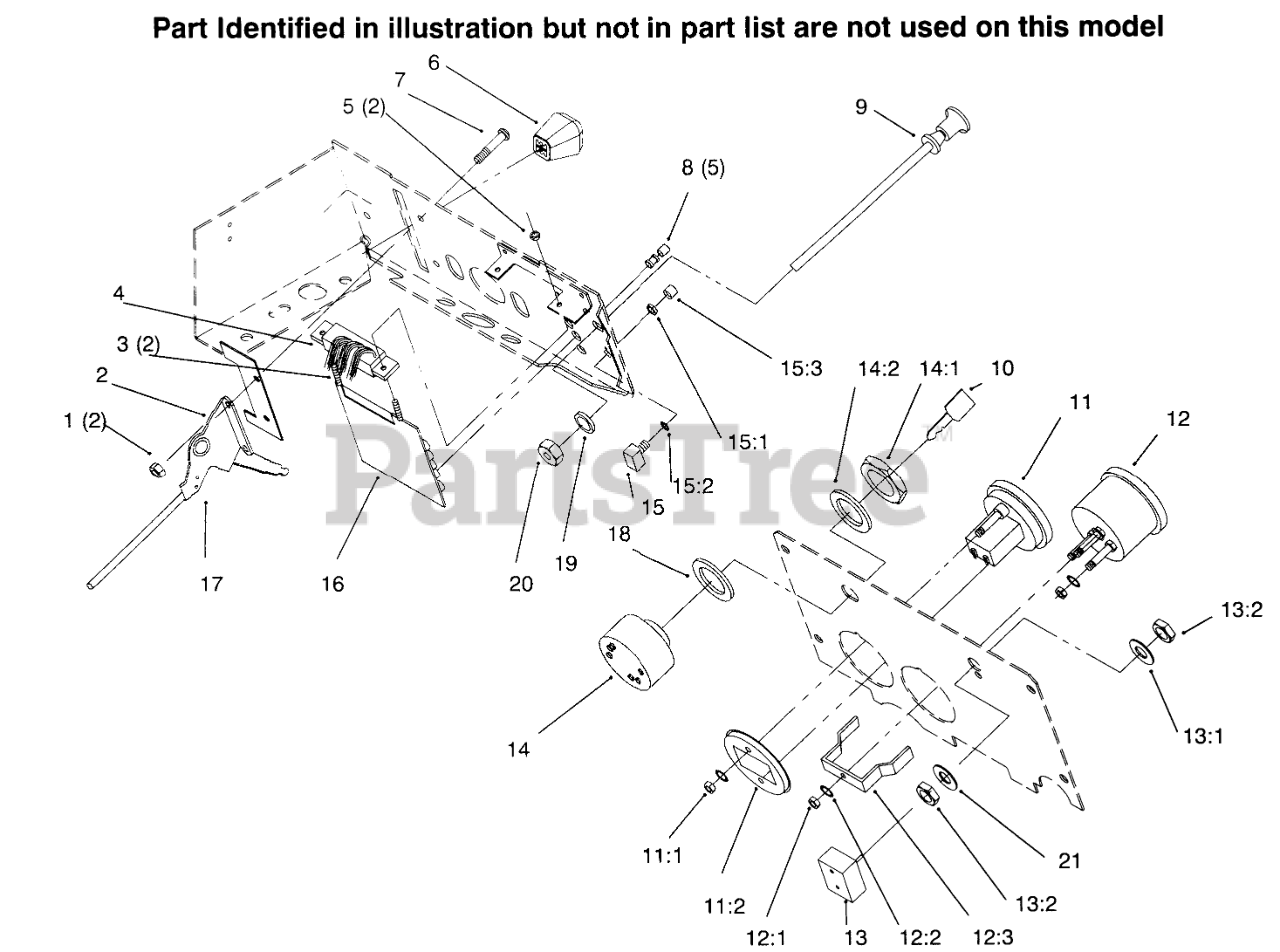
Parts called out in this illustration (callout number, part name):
2	Washer
3	Screw
4	P.C.-BOARD HARNESS
5	NUT-HEX
7	SCRW-PHC
8	ASSY LENS & BUSHING
9	CONTROL CHOKE
10	KEY-IGNITION
11	Hourmeter
12	VOLTMETER
13	SWITCH-LIGHTS
14	KEY SWITCH ASM
15	SWITCH-PUSH BUTTON
16	Board-Pc
17	CONTROL-THROTTLE
18	WASHER
19	WASHER-FLAT
20	NUT-HEX PALNUT
21	WASHER
